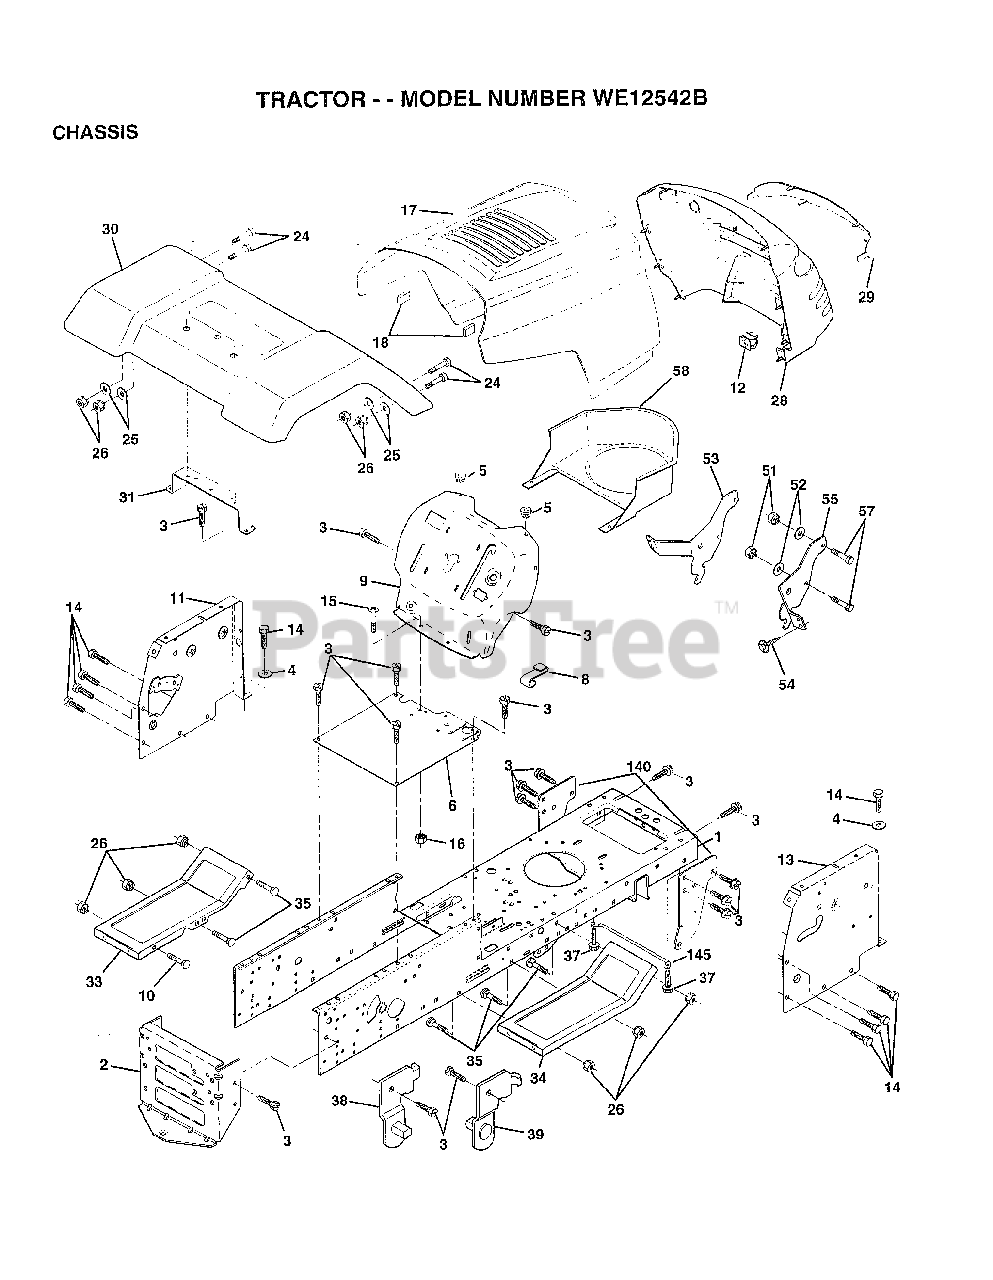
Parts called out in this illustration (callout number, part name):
3	SCREW
4	WASHER
5	BUMPER-HOOD/DASH
6	"SADDLE-SLKSCR,5SP"
8	CLIP.RETAINER
9	DASH SILKSCREEN
11	"PANEL-DASH,LH"
12	CLIP.TINNERMAN
14	SCREW LT
15	SCREW
17	HOOD.STEEL.ASSY
24	BOLT
25	WASHER
26	NUT
28	GRILLE-MS428
29	LENS GRILLE
30	FENDER PNT LT
31	BRKT FENDER
33	FOOTREST.LH.PERF.
34	FOOTREST.RH.PERF.
35	BOLT
37	SCREW LT
38	BRACKET ASM LH
39	BRACKET ASM RH
51	NUT
52	WASHER
53	BRACKET.GRILLE.LH
54	SCREW.HEX.WS.HD
55	BRACKET.GRILLE.RH
58	AIR DUCT
140	BRKT SUSPENSION
145	"ROD POVOT,CHASSIS"
